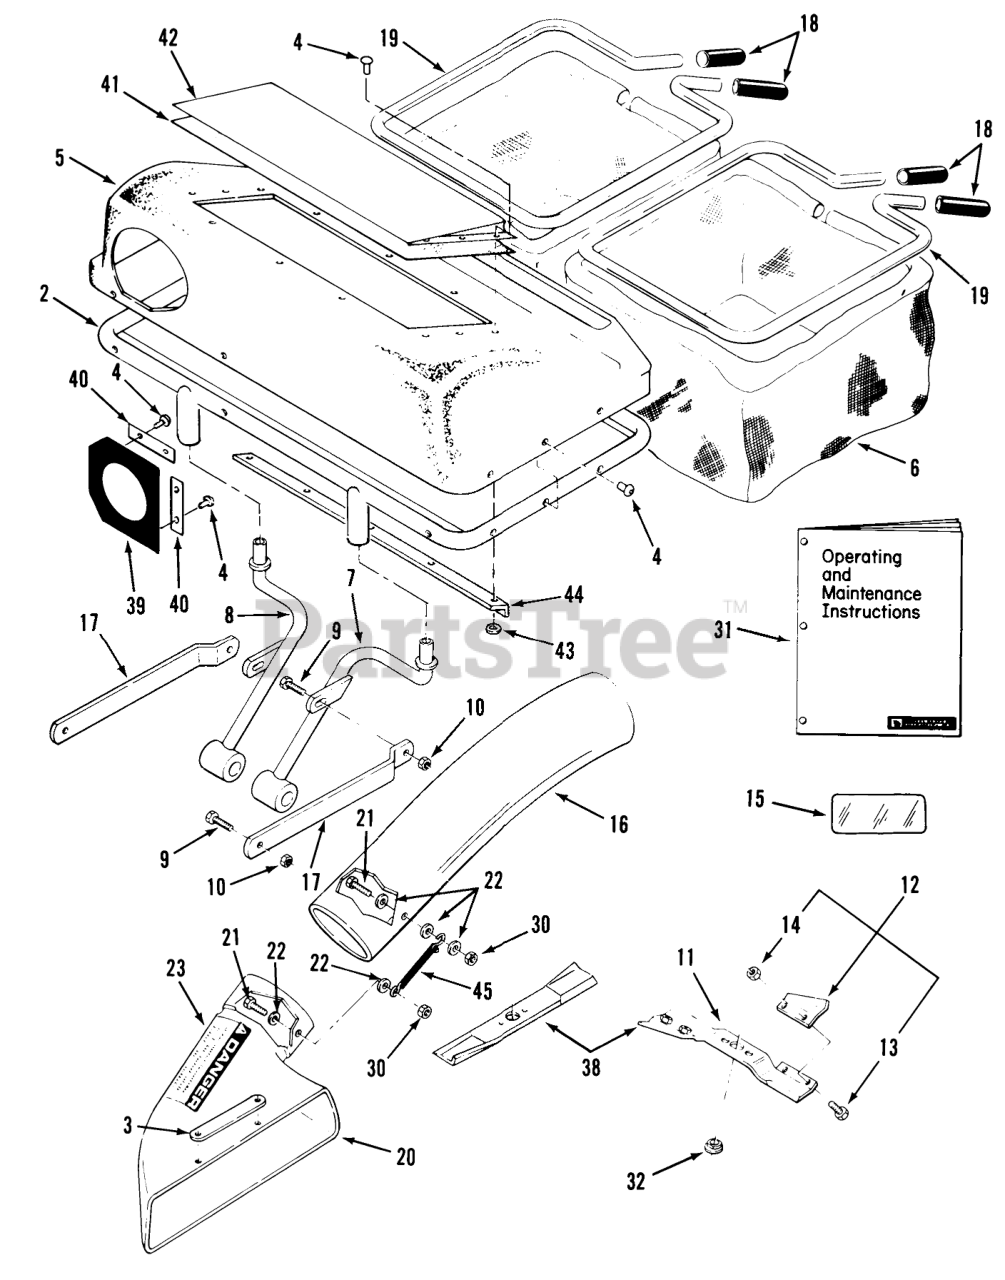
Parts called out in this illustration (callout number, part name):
2	Frame
3	PLATE-ELBOW B
4	RIVET-BLIND
5	TOP-BAG'R (37")
6	BAG-BLACK(37"TWIN)
7	ASSY QUICK ATTACH B
8	ASSY QUICK ATTACH B
9	Bolt
10	Nut
11	High Lift Blade (includes item 12) RH
12	Lift Tab Kit (includes items 13 & 14)
13	BOLT 5/16-18X5/8
14	NUT-LOCK 5/16-18
15	DECAL-OVERLAY
16	Tube (includes items 21, 22 & 30)
17	BRACE B
18	GRIP
19	FRAME BAG B
20	Elbow (includes items 21, 22, 23 & 30)
21	Bolt
23	BRACKET-SEAT MOUN R
30	Nut
31	Operating and Maintenance Instructions
32	SPACER BLADE
38	Blade Kit (includes LH blade, RH blade with tabs, hardware and spacer)
39	SEAL-CHUTE
40	STRAP-SEAL
41	Top Screen
42	Screen Cover
43	Washer
44	Top Stiffener
45	STRAP
